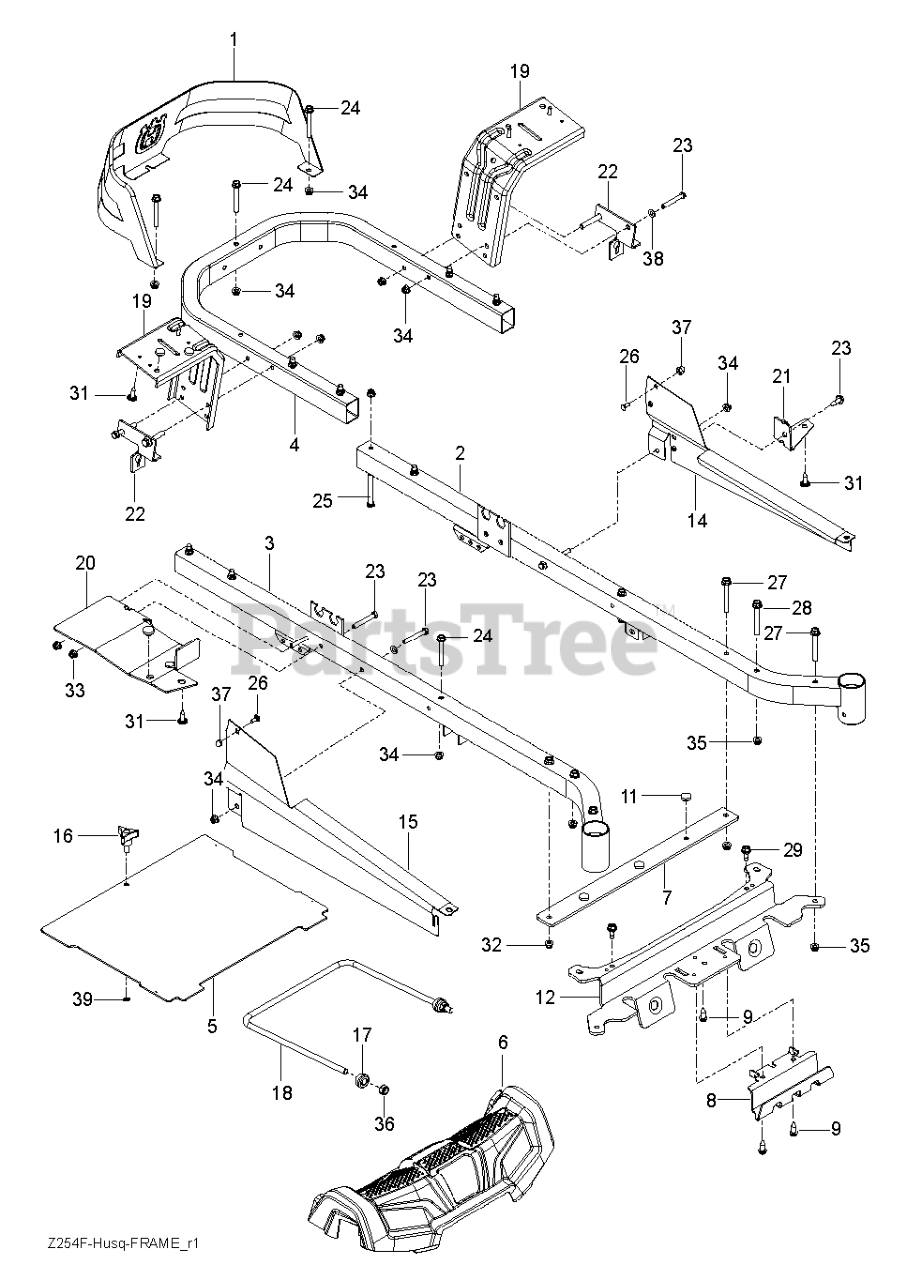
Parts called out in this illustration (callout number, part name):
1	GUARD.ENGINE.HUSQ.RZ.X498
2	FRAME.TUBE.RZ.MAIN.WELD.RH.ORG
3	FRAME.TUBE.RZ.MAIN.WELD.LH.ORG
4	TUBE.PNT.FRAME.RER.HUSQ.23".RZ
5	PLATE FOOT ORANGE X668
6	COVER.FOOTREST.REFRESH.ASM
7	FOOTREST.PLATE.SUPPORT.X431
8	SKID.PLATE.PNT.RZ.REF.SIVER
9	BOLT.5/16HEX.WHS.HD
11	GROMMET.BUMPER
12	CROSS.PNT.MEMBER.BLK
14	COVER.RAIL.RH.RZ.X668
15	COVER.RAIL.LH.RZ.X668
16	KNOB W/STUD
17	BUSHING SPHERICAL SUSP. FRONT
18	LINK, FRONT SUSP.
19	FENDER.SUPPORT.PNT.X431
20	SUPPORT.PNT.RH.CONSOLE.FRONT
21	SUPPORT.PNT.LH.CONSOLE.FRONT
22	BRKT ROD.BYPASS.EZT.X431
23	BOLT.FIN HEX 5/16-18UNC X2 1/4
25	BOLT.HEX.FIN.3/8-16 X 3.GR5
26	BOLT.CARRIAGE.5/16-18.7/16
27	HHFS 3/8-16 X 3 GRD 5 ZD
28	BOLT SHOULDER,FLANGED,3/8-16X3
29	BOLT.5/16-18.THRD.ROLL.SHOULDR
31	SCREW.#10 X 0.750.BOS
32	SCREW.#10 X 0.500
33	NUT LOCK HEX FLANGE 5/16-18
34	5/16-18 NYLOC FLANGE NUT
35	NUT 3/8-16 HEX FLG NYLOC ZD
36	7/16-14 HEX NUT W/NYL RING ZD
37	NUT ACORN,FLANGED,5/16-18
38	WASHER
39	WASHER 5/16"
